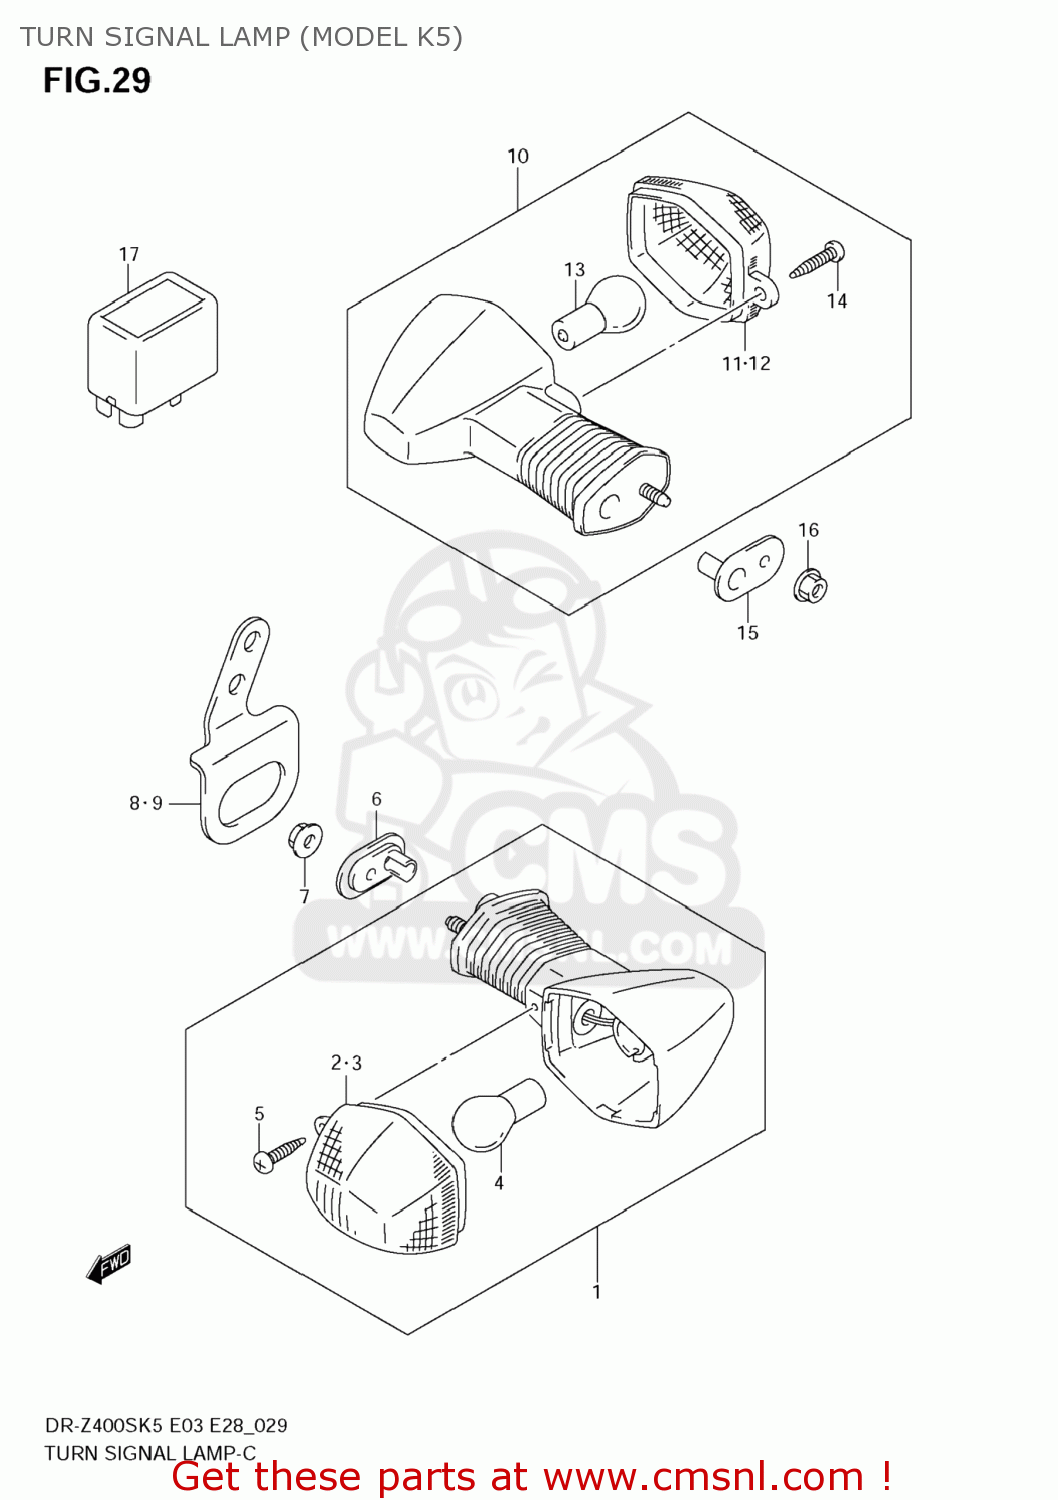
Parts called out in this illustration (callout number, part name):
1	LAMP ASSY,FR TURN SIGNAL,R
2	LENS
3	LENS
4	BULB(12V21W)
5	SCREW
6	PLATE,TURNSIGNAL LAMP
7	NUT
8	BRACKET,FR TURNSIGNAL,R
9	BRACKET,FR TURNSIGNAL,L
10	LAMP ASSY,RR TURNSIGNAL,R
11	LENS
12	LENS
13	BULB(12V21W)
14	SCREW
15	PLATE,TURNSIGNAL LAMP
16	NUT
17	RELAY ASSY,TURNSIGNAL LAMP
